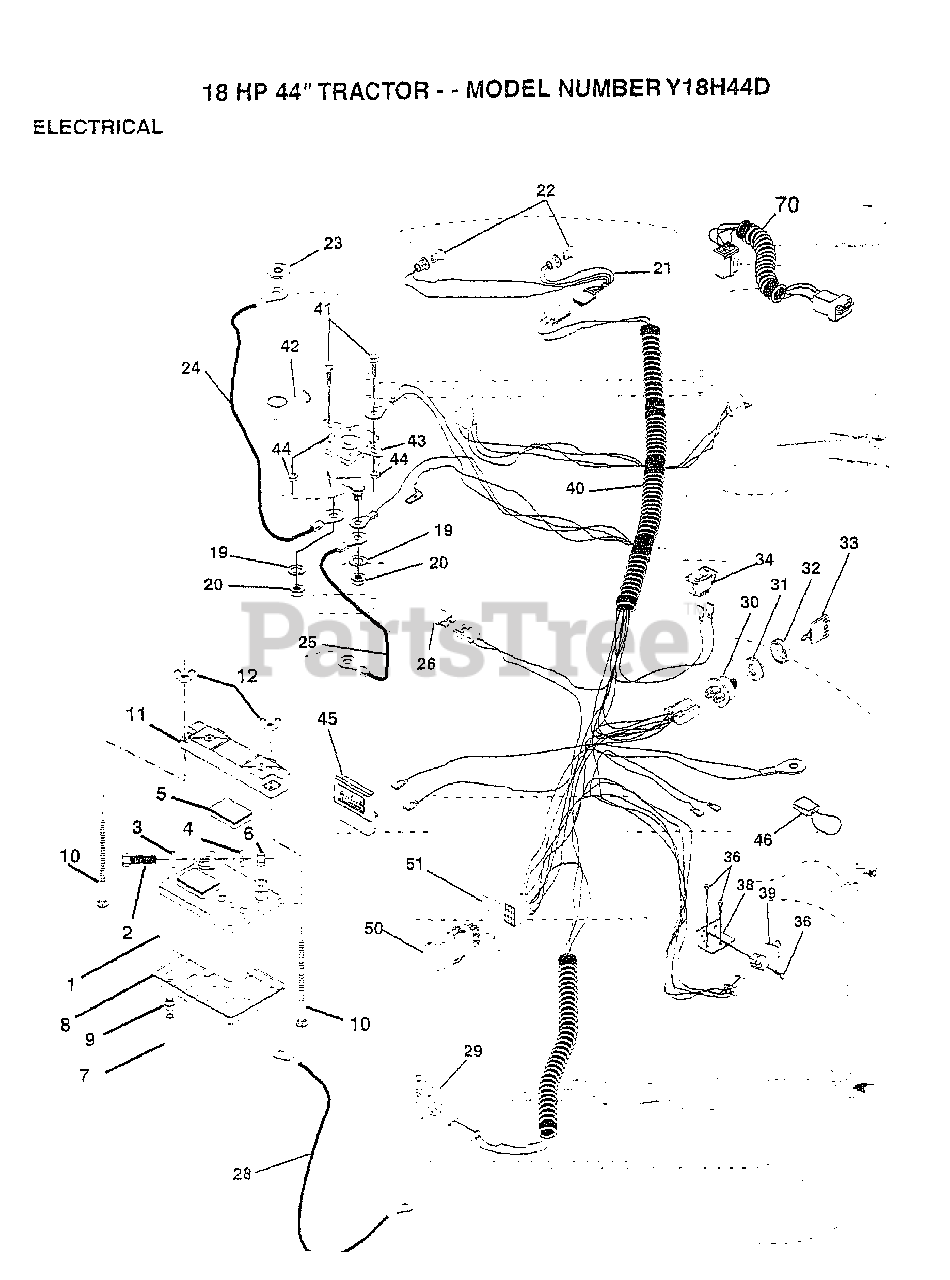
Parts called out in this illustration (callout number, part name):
2	BOLT LT
3	WASHER
4	LOCKWASHER
5	"CAP,BATTERY "
7	"DRAIN TU T, BATT"
8	"TRAY T, BATTERY"
9	HOSE CLAMP T
10	BOLT
20	NUT
21	"HARNESS,LIGHT SOC"
22	HEADLAMP BULB
23	LOCKWASHER
24	CABLE-BATTERY T
25	"CABLE T, BATTERY"
26	FUSE HYT
28	CABLE T
29	SWITCH SEAT
32	COVER KEY SWITCH
33	KEY MLD GEN DELTA
34	SWITCH LT
36	SCREW
38	BRACKET LT
39	SWITCH INTERLOCKT
40	HARNESS.IGN.PTO
41	BOLT HXHD FIN
44	NUT HXKEP 1/4X20
45	AMMETER
46	PROTECTION LOOP
51	RING RETAIN PTO
70	HARNESS.ENG.KOHL
